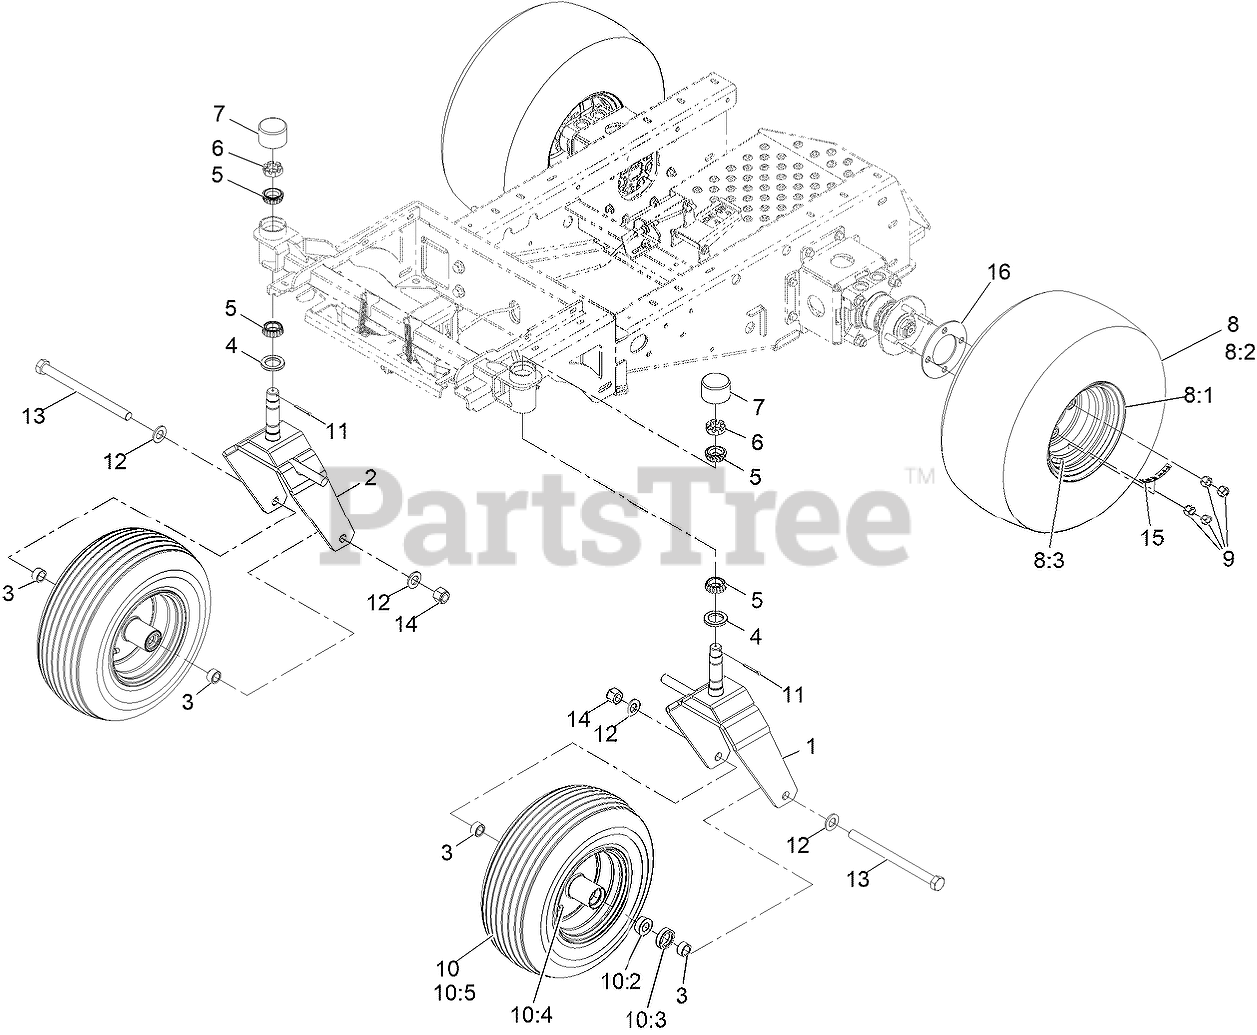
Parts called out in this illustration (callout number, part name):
1	X-REF TO 135-5441-03
2	X-REF TO 135-5446-03
3	SPACER-AXLE
4	SEAL-GREASE
5	CONE-BEARING, OUTER
6	NUT-SHH
7	CAP-DUST, RUBBER
8	WHEEL AND TIRE ASM
8:1	Rim-8 X 7, Black
8:3	Stem-Valve
9	NUT-LUG
10	WHEEL AND TIRE ASM
10:2	TIRE-RIB
10:3	BEARING-CONE, TAPERED ROLLER
10:4	VALVE
10:5	SEAL-CASTER
11	Pin-Cotter
12	WASHER-FLAT
13	SCREW-HH
14	NUT-LOCK, NI
15	DECAL-TORQUE, WHEEL HUB LUG
16	SPACER-WHEEL
